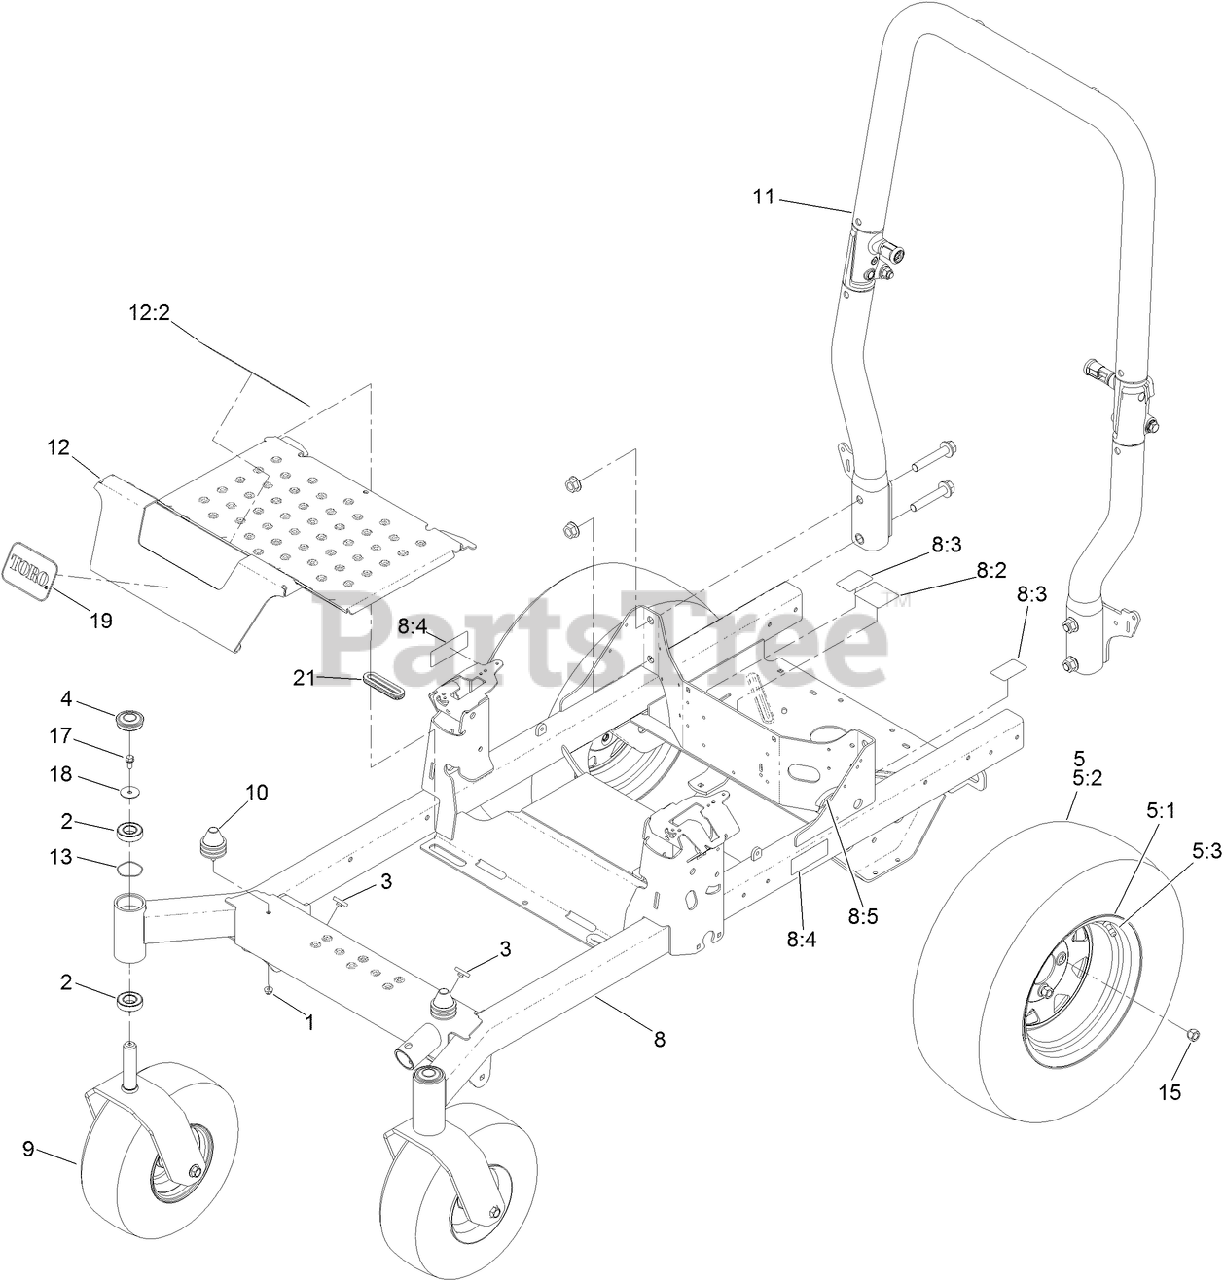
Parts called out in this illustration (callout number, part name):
1	NUT-HF, NI
2	BEARING-BALL
3	BUMPER-PUSH-IN, RUBBER
4	CAP-GREASE
5	WHEEL AND TIRE ASM
5:2	TIRE
5:3	STEM-VALVE
8	FRAME ASM
8:2	DECAL-ROUTING, BELT
8:3	DECAL-RELEASE, DRIVE
8:4	DECAL-WARNING
8:5	STRIP-SEAL
9	FRONT CASTER ASM (W/FORK)
10	ISOLATOR
11	ROPS ASM
12	PAN-FLOOR
12:2	DECAL-DANGER
13	SPRING
15	NUT-LUG
17	SCREW-HHF
18	WASHER-FLAT
19	DECAL
21	GROMMET-RUBBER
